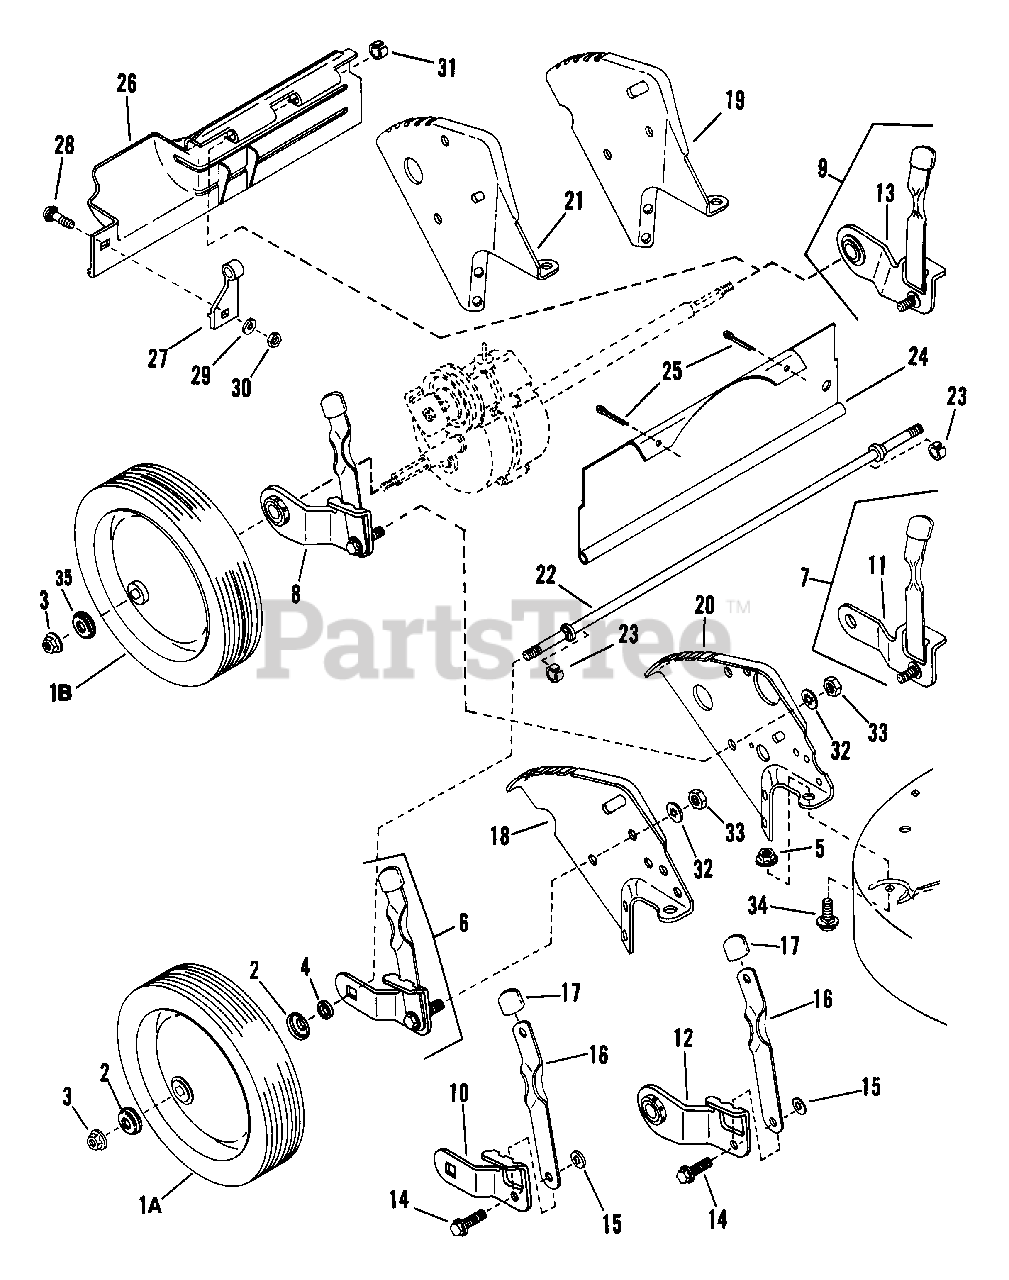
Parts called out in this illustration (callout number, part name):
1A	WHEEL, 9 x 1.75 Steel Rim
1B	WHEEL, 9 x 1.95 Steel Rim
2	HUB-CAP
3	NUT, 7/16-20 Hex Center Lock
4	WASHER, Steel
5	NUT, 5/16-18 Hex Flang Lock
6	WHEEL ARM ASSEMBLY (Front Left & Rear Right) Square opening-
7	WHEEL ARM ASSEMBLY (Front Right & Rear Left) Round opening-
8	ASSEMBLY, Wheel Arm (Rear Right "P" Models)
9	ASSEMBLY, Wheel Arm (Rear Left "P" Models)
10	ARM (Square Axle End)
11	ARM (Round Axle End)
12	ARM & BEARING ASSEMBLY, Rear Right "P" Models
13	ARM & BEARING ASSEMBLY, Rear Left "P" Models
14	BOLT, 5/16-18 x 1 Shoulder
15	RETAINER, 5/16 Bolt
16	LATCH, Height Adjusting
17	GRIP, Latch
18	BRACKET, Right Rear Wheel
19	BRACKET, Left Rear Wheel
20	BRACKET, Right Rear Wheel
21	BRACKET, Left Rear Wheel
22	AXLE, (Rear on Push Models also front on all)
23	RING
24	GUARD, Rear Foot
25	COTTER PIN, 1/8 x 1-1/2
26	GUARD, Rear Foot
27	SUPPORT, Foot Guard
28	BOLT, 1/4-20 x 1/2 Short Neck Carriage Gr.5
29	WASHER, 1/4 Int. Tooth Lock
30	NUT, 1/4-20 Hex
31	RING
32	WASHER, 5/16 Int. Tooth Lock
33	NUT, 5/16-18 Hex
34	BOLT, 5/16-18 x 1/2 Short Neck Carriage
35	HUB-CAP, Deep Dish
